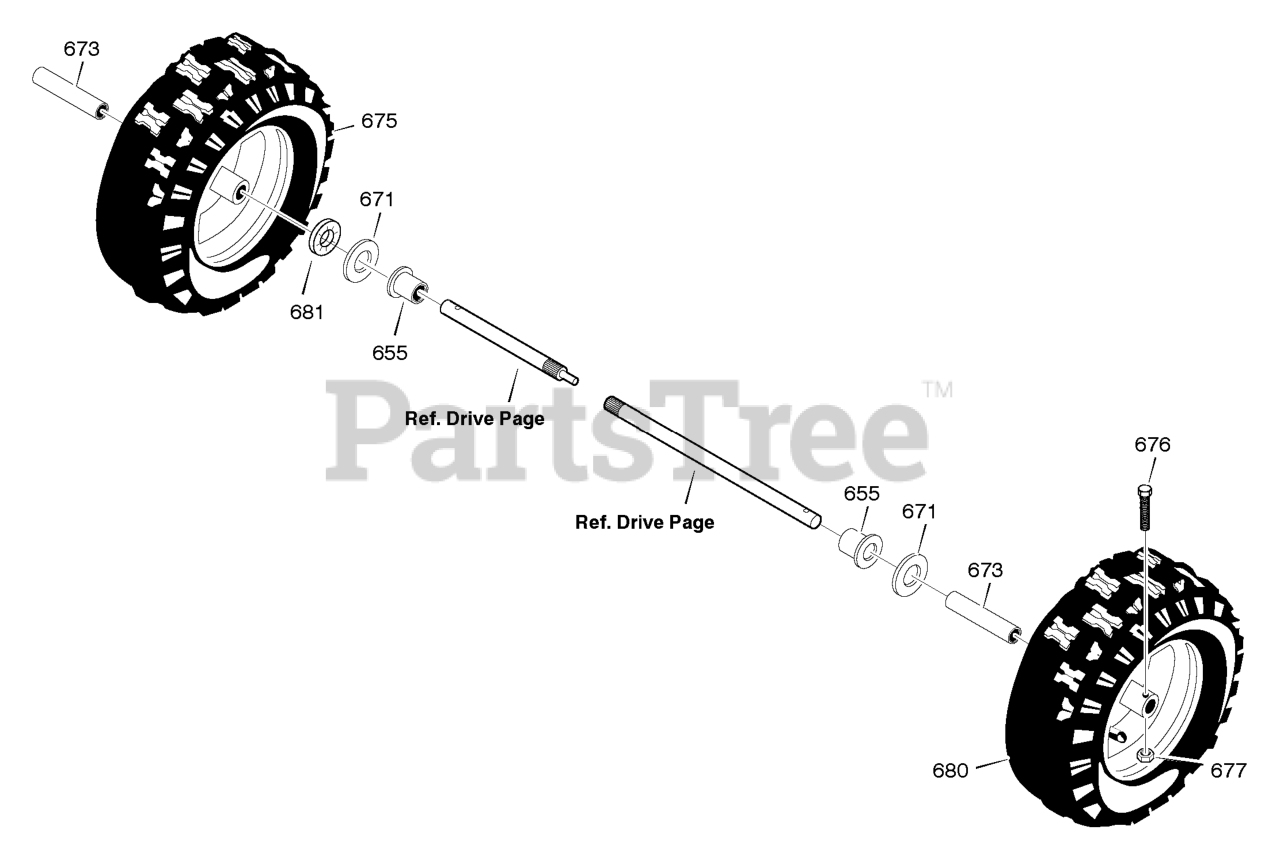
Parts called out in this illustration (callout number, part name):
655	BEARING, AXLE
671	FLATWASHER
673	BUSHING, WHEEL
675	TIRE & RIM, RIGHT
676	SCREW, 1/4-20X1.75 HH
677	NUT, 1/4-20 HEX NYLOCK
680	TIRE & RIM, LEFT
681	RETAINER
